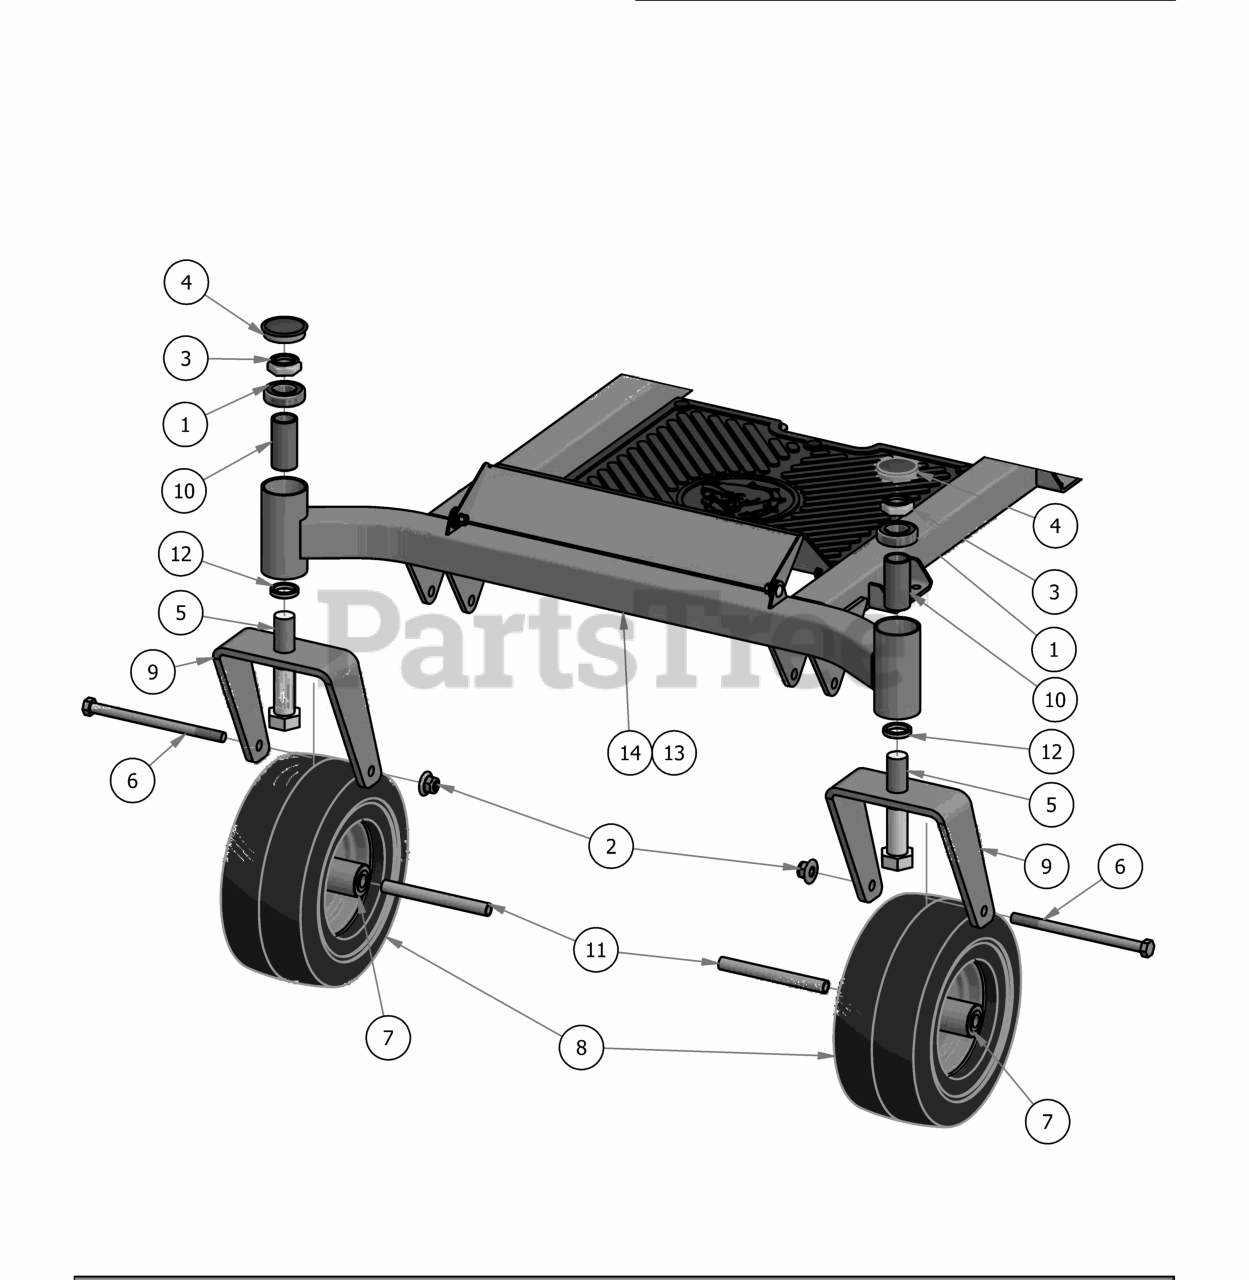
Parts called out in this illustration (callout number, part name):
1	Caster Bearing 2016 - 1641 Bearing
2	1/2-13 Nylon Flange Nut
3	1" Fine Thread 1/2 Nylock Nut
4	2017 Bearing Cover
5	1-14 x 5 Hex Bolt Grade 8 Zinc Yellow
6	1/2 -13 x 7.5 Hex Bolt Grade 5
7	Front Wheel Bearing
8	11x6-5 front tire & wheel assembly
9	2017 MZ Front fork
10	2016 Front Bearing Spacer
11	Front Wheel Spanner
12	1" x .25" Spacer
13	2017 MZ/ZT 54"-60" Frame
14	2017 MZ/ZT 42"-48" Frame
